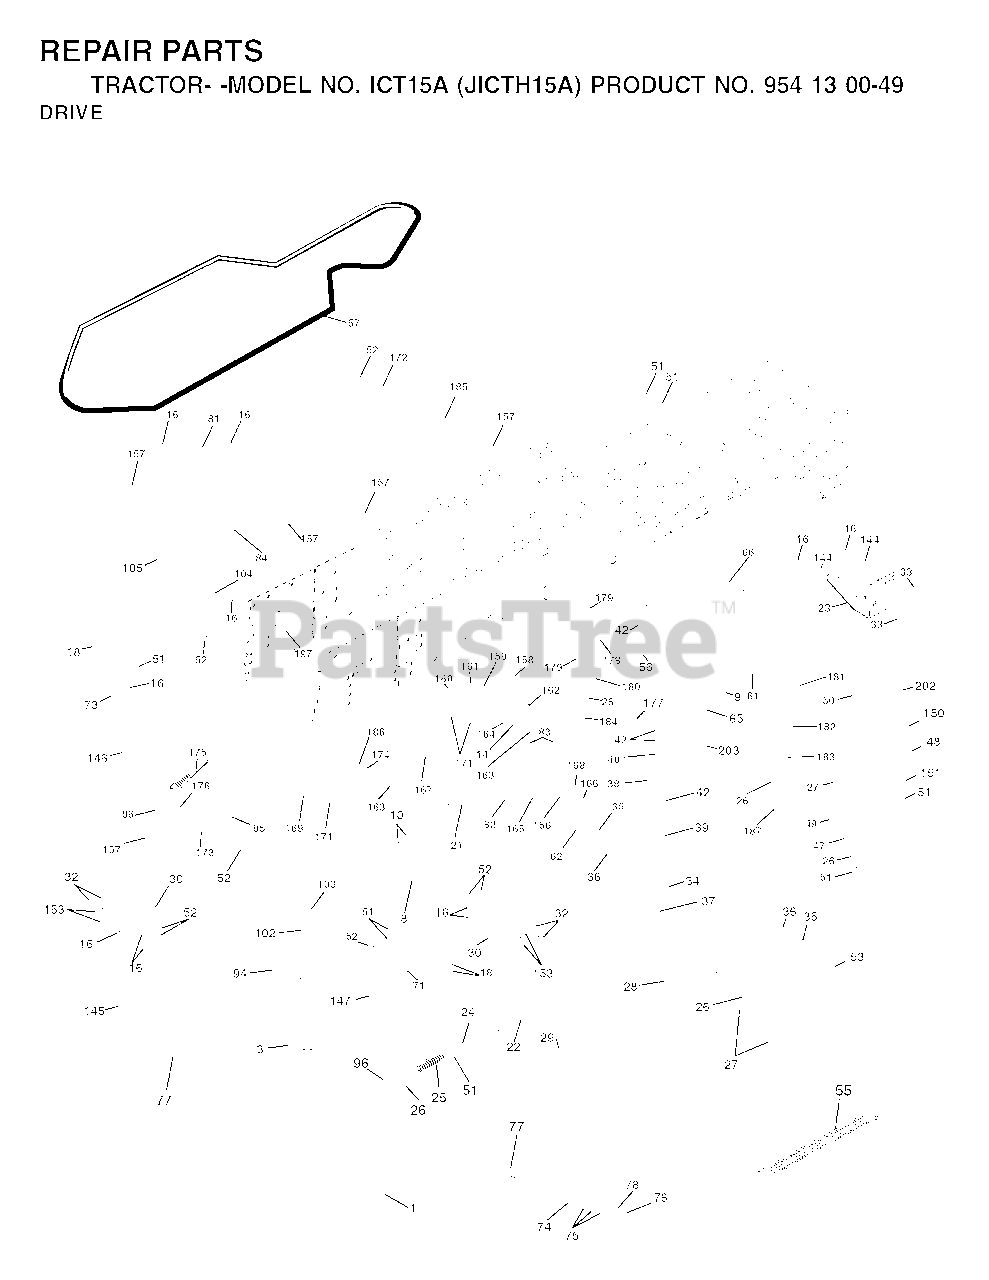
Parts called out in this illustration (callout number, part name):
3	PULLEY, TRANSAXLE
8	ROD SHIFT
9	CLUTCH ASSY
10	PIN COTTER
14	LOCKWASHER
16	NUT.71038.31-18.HEX.NYLOCK
21	PISTOL KNOB
24	NUT
25	SPRING ROD LT
27	COTTER PIN
28	ROD BRAKE PARK LT
29	PLUNGER CAP
30	BRKT, TRNSXLE MNT 20"
32	BOLT
33	BOLT
35	BEARING.NYLON
36	WASHER LT
37	DRIVE PIN
38	PULLEY.FLAT
42	WASHER
47	IDLER PULLEY
48	BELLCRANK, CLUTCH
49	RETAIN BELT
50	BOLT
51	LOCKNUT
52	LOCKNUT
53	LINK, CLUTCH LT
55	SPRING, RETURN LT
57	V-BELT.0650.CRD.TRACTOR
61	SCREW 3/8-16X3/4
62	COVER, PEDAL
65	LOCKWASHER
66	KEEPER BELT ENGINE
71	STRAP LH TORQUE
73	STRAP TORQUE RH HYDRO
74	SPACER SPLIT
76	E-RING LT
77	SQUARE KEY
82	SPRING,TORSION
83	WASHER
84	LINK TRANSAXLE
94	FAN 7" HYDRO
96	RETAINER M
103	NUT.HEX.1/2-20
104	CONTROL ARM
144	WASHER
146	BOLT
150	BUSHING.BELLCRANK.GRD.DR
151	WASHER 12/32X2X10GA
153	BOLT RB
156	WASHER.SRRTD.5/16
157	BOLT SHOULDER 5/16-18
158	BRACKET
159	HUB
161	BOLT
162	NUT.CROWNLOCK.1/4
165	RP BRACKET
167	BRACKET
168	BOLT.SHOULDER.5/16-18X
169	PLATE.FASTENING.CROSS.SHAFT
174	LOCKWASHER
175	SPRING.BYPASS.CRD
176	WASHER
180	PULLEY.FLAT.IDLER
182	KEEPER BELT
183	PULLEY.V-IDLER
184	SCREW.HXWSH.3/8
187	SCREW
197	NYLINER SNAP 5/8" ID
202	BOLT.3/8-16X1.50
